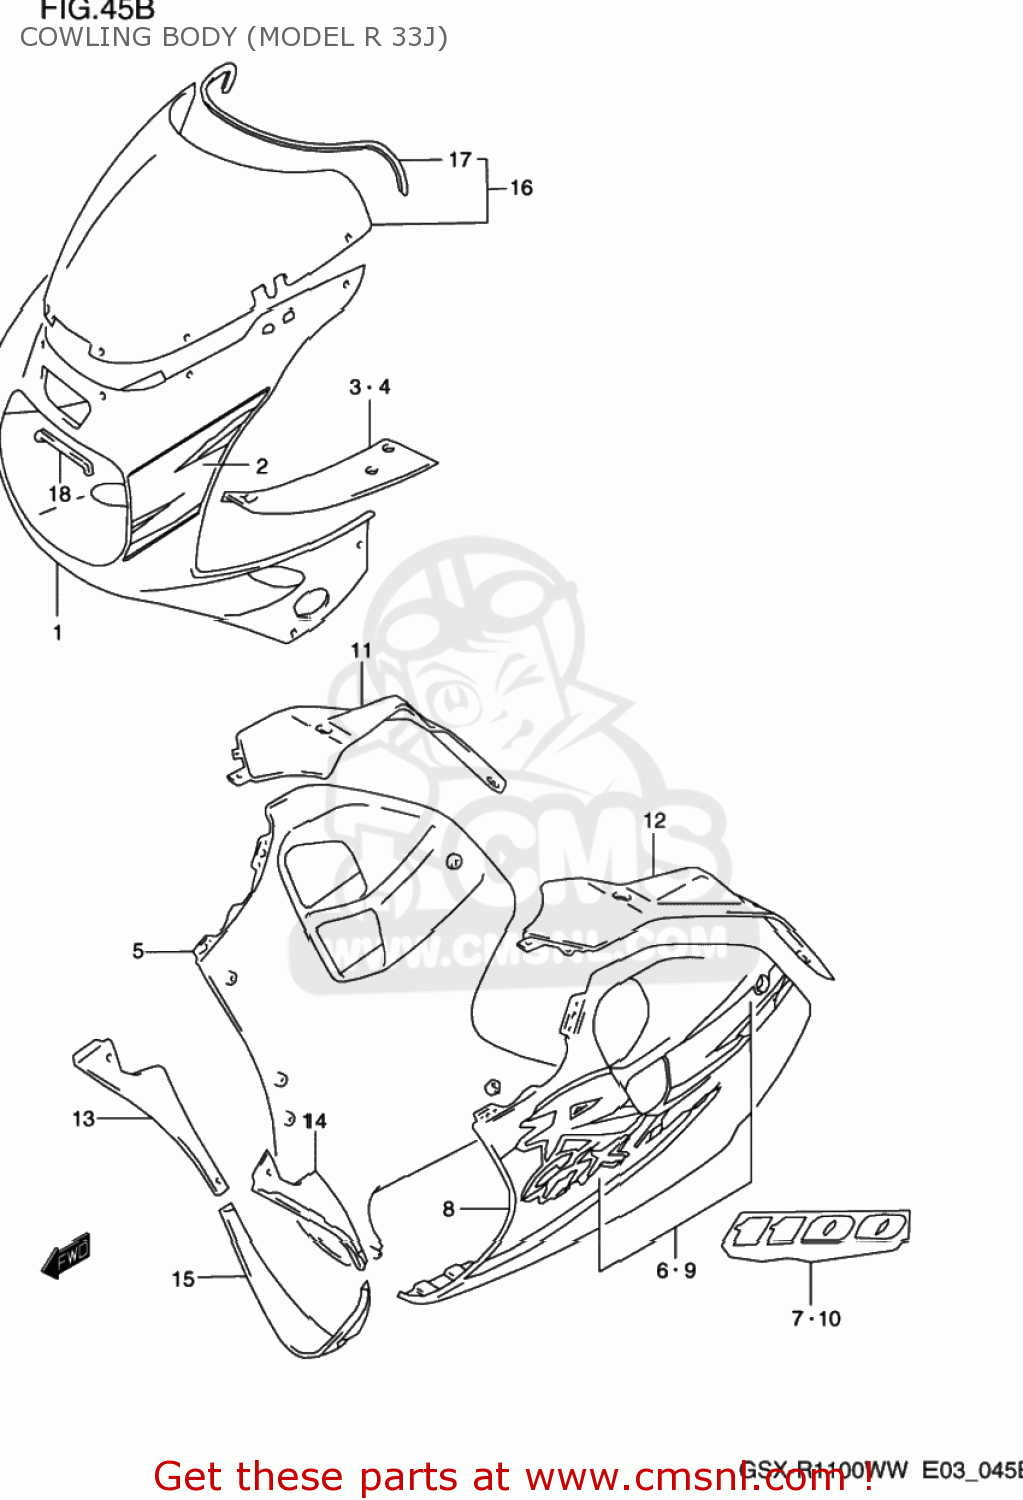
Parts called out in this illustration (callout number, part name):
1	COWLING ASSY,BODY
2	TAPE SET,COWLING BODY
3	PANEL,UPR,R
4	PANEL,UPR,L
5	COWLING ASSEMBLY,UNDER,RIGHT
6	TAPE SET,COWL UNDER,R
7	EMBLEM,COWLING UNDER
8	COWLING ASSY,UNDER,L
9	TAPE SET,COWL UNDER,L
10	EMBLEM,COWLING UNDER
11	PANEL,LWR,R
12	PANEL,LWR,L
13	COWLING,UNDER INNER,R
14	COWLING,UNDER INNER,L
15	COWLING,UNDER CTR
16	SCREEN SET,WIND
17	MOLDING,WINDSCREEN
18	CUSHION,FR POSITION LAMP
